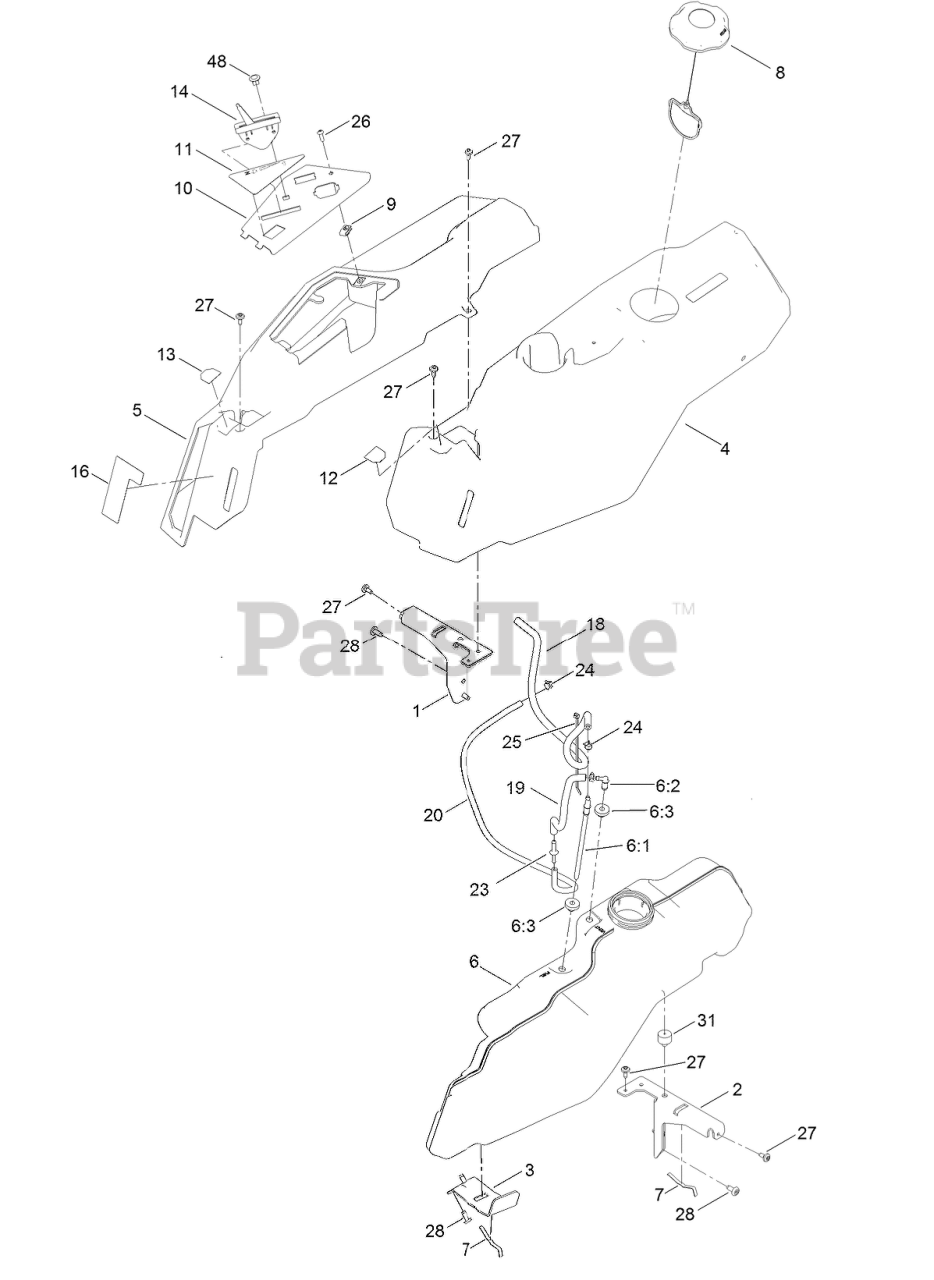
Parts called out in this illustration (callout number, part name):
1	SUPPORT-POD, RH
2	SUPPORT-POD, LH
3	SUPPORT-TANK, FUEL
4	POD-LH
5	POD-RH
6	FUEL TANK ASM
6:1	CONNECTOR-ELBOW, 90 DEG
6:2	FITTING-PLASTIC
6:3	BUSHING
7	SPRING
8	CAP-FUEL, RATCHETING
10	PANEL-CONTROL
11	DECAL-PANEL CONTROL
12	DECAL-CONTROL LEVER, LH
13	DECAL-CONTROL LEVER, RH
14	CABLE-THROTTLE AND CHOKE
16	DECAL-SMART SPEED
18	HOSE-FUEL
19	HOSE-FUEL
20	HOSE-FUEL
23	ADAPTOR-ORIFICE
24	CLAMP-HOSE
25	TIE-CABLE
26	SCREW-PRH
27	SCREW-SHOULDER
31	BUMPER-GROMMET
48	PLUG-DASH
